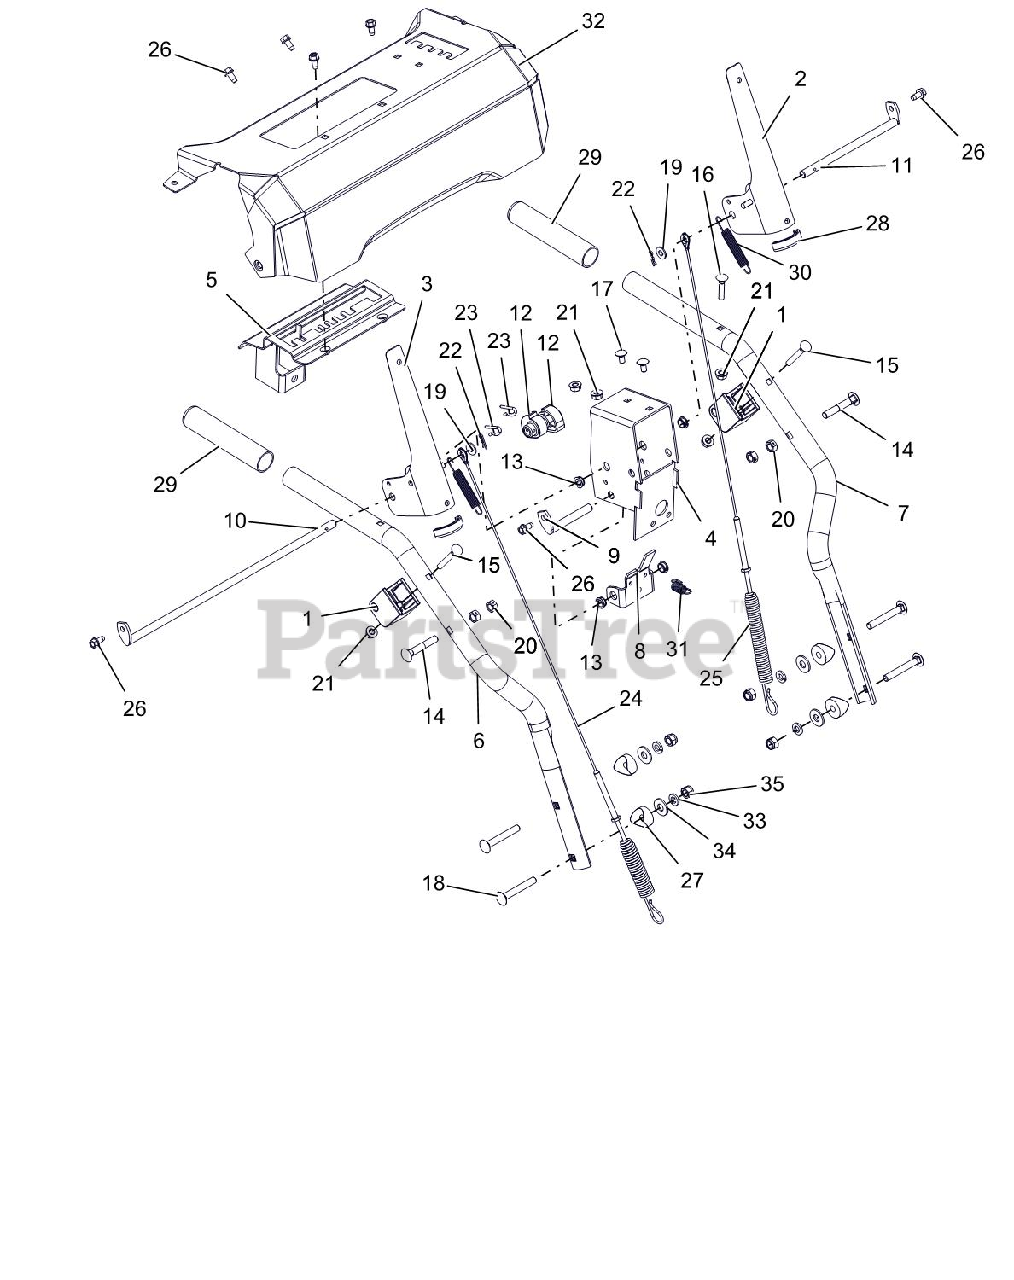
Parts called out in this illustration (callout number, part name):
1	BLOCK, CLUTCH PADDLE
2	LEVER, CLUTCH-LH
3	LEVER, CLUTCH-RH
4	WELDMENT, BRACKET INTERLOCK
5	WELDMENT, DETENT PLATE-COMPACT
6	HANDLEBAR, UPPER - RH
7	HANDLEBAR, UPPER - LH
8	BRACKET, INTERLOCK ARM
9	ROD, INTERLOCK PIVOT
10	ROD, PADDLE MOUNT - LONG
11	ROD, PADDLE MOUNT - SHORT
12	CAM, INTERLOCK
13	BUSHING, POLYLINER-.38 SNAPIN
14	BLT-RDHDXLSQNK .31-18X2.0 G5YZ
15	BLT-RDHDXLSQNK .25-20X2.0 G5YZ
16	BLT-RDHDXLSQNK.25-20X1.25 G5YZ
17	BLT-RDHDSQNK .25-20X.50 G5YZ
18	BLT-RDHDSQNK .31-18X2.25 G5YZ
19	WSHR-FL-STL.281X.62X.065 YWZC
20	NUT-LK-CTR .31-18 YWZC
21	NUT-LK-TOP-FLG .25-20 YWZC
22	PIN-HAIR INT .06X.18X.77
23	PIN, SPRING CLIP
24	CABLE, AUGER (DELUXE & PRO)
25	CABLE, UPPER TRACTION
26	SCR-TAP .25-20X.50 HWH TR YWZ
27	SPACER, HANDLEBAR
28	EDGING, CLUTCH PADDLE - 2.00"
29	GRIP,HANDLE-GRAY
30	SPRING, EXTENSION
31	SPRING-EXT .047X.438X1.45
32	CONTROL PANEL W/DECAL, BRUSH
33	WSHR-LK .312X.097 HVY YWZC
34	WSHR-FL-STL.38X.875X.083 YWZC
35	NUT-LK-NYL .312-18 YWZC
